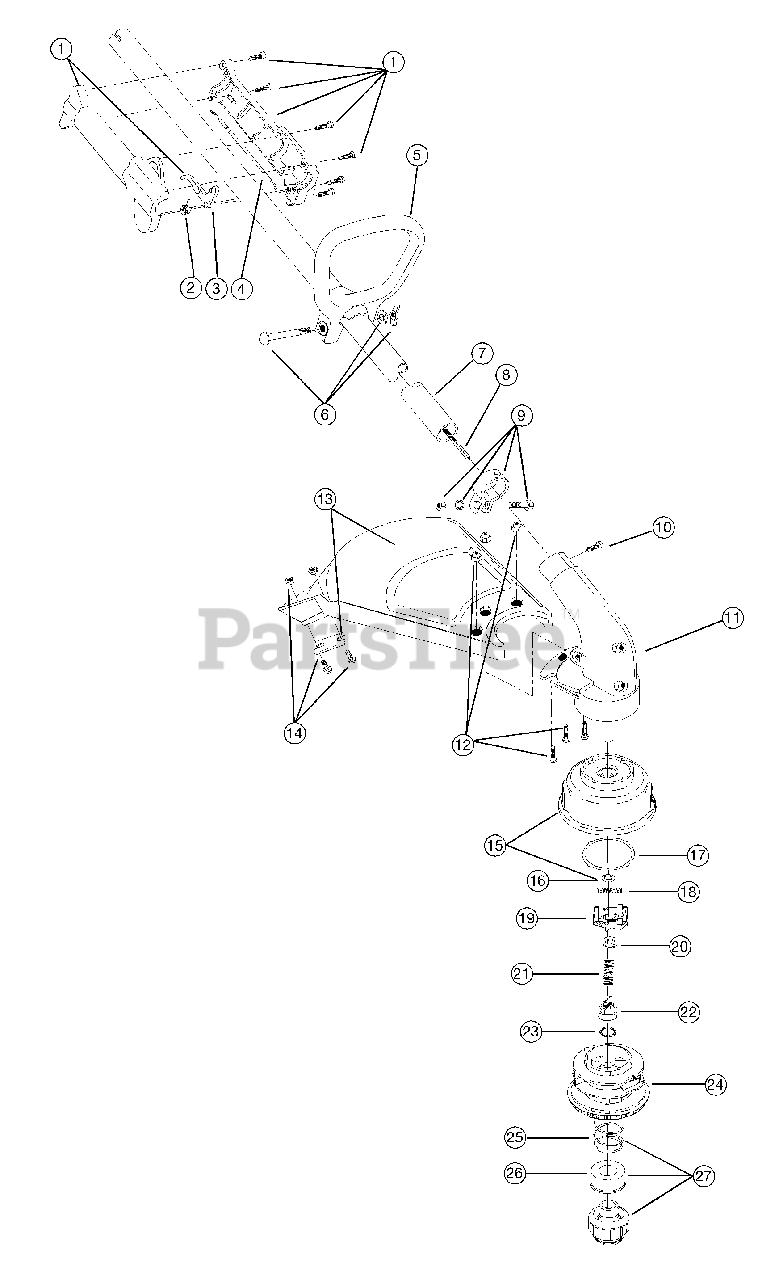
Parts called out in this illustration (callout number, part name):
1	Throttle Housing and Trigger Assembly
2	Throttle Trigger Spring
3	Throttle Trigger
4	Throttle Cable Assembly
5	D-Handle Assembly
6	D-Handle Hardware
7	Drive Shaft Housing Assembly
8	Flexible Drive Shaft
9	Lower Clamp Assembly
10	Anti-Rotation Screw
11	Gearbox Assembly
12	Shield Mounting Hardware
13	Shield and Blade Assembly
14	Blade Assembly
15	Outer Spool and Eyelet Assembly
16	Retainer
17	Thrust Washer
18	Small Spring
19	Slider
22	Plunger
24	Inner Reel
25	Large Spring
26	Foam Seal
27	Bump Head Knob Assembly
